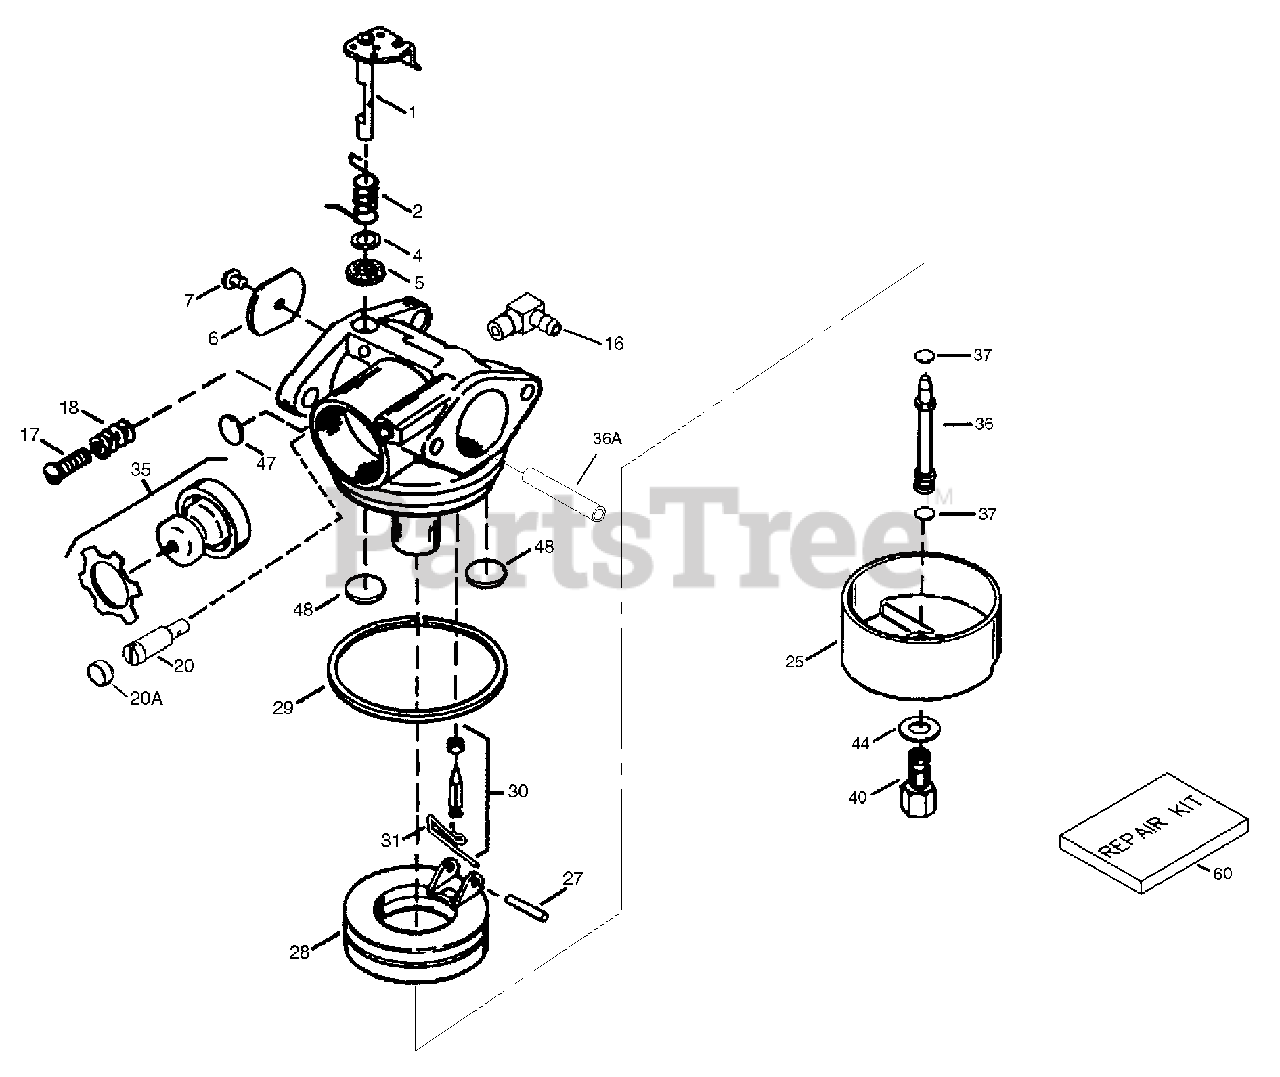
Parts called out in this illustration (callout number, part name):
1	Throttle Shaft & Lever Assembly
2	Throttle Return Spring
4	Dust Seal Washer
5	Dust Seal (Throttle)
6	Throttle Shutter
7	Shutter Screw
16	Fuel Fitting
17	Throttle Crack
18	Tension Spring
20	Idle Restrictor Screw
20A	Idle Restrictor Screw
25	Float Bowl
27	Float Shaft
28	Float
29	Float Bowl "O" Ring
30	Inlet Needle, Seat, & Clip (Incl. 31)
31	Spring Clip
35	Primer Bulb/Retainer Ring
36	Main Nozzle Tube
36A	Bowl Vent Tube
37	O-Ring, Main Nozzle Tube
40	High Speed Bowl Nut
44	Bowl Nut Washer
47	Welch Plug, Idle
48	Welch Plug, Atmospheric Vent
60	Repair Kit
